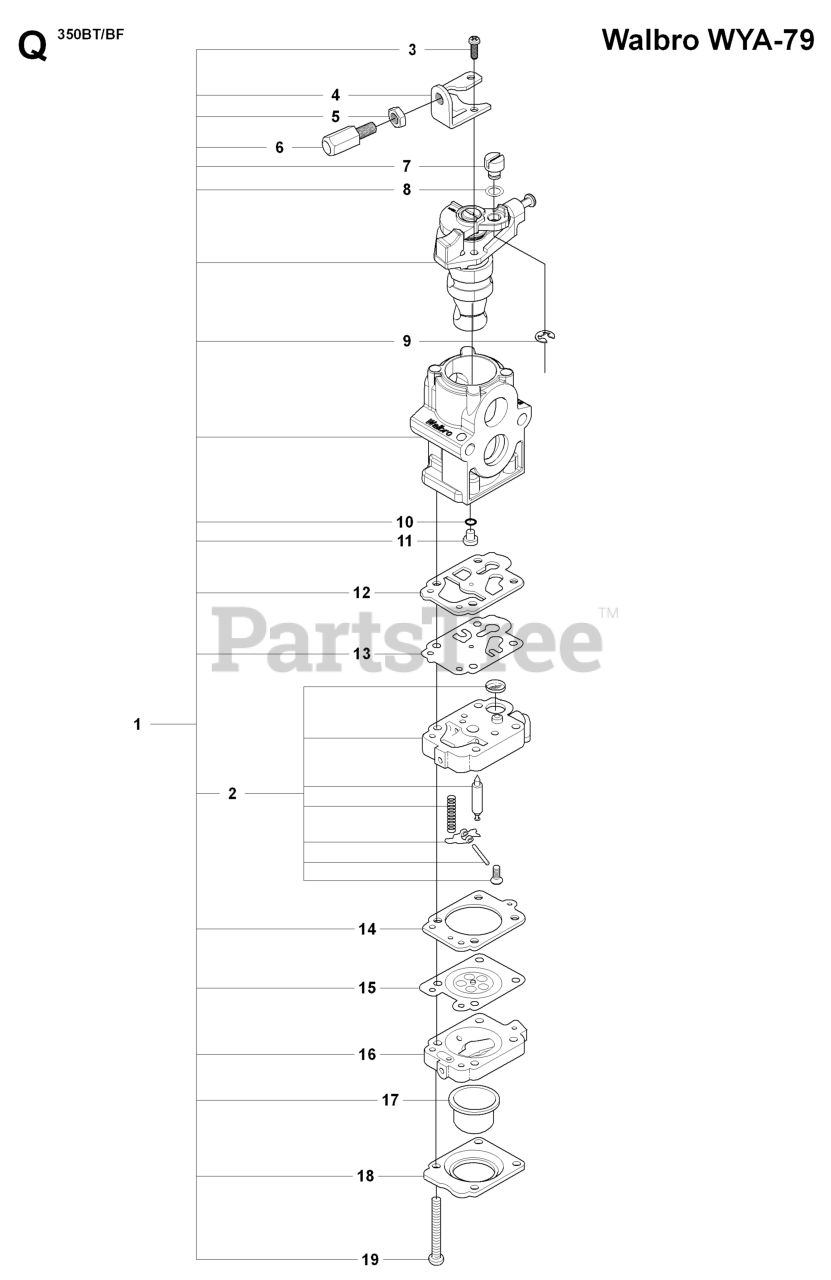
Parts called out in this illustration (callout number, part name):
1	CARBURETTOR
2	BODY-A-PUMP
5	NUT
6	ADJUSTER
11	JET
